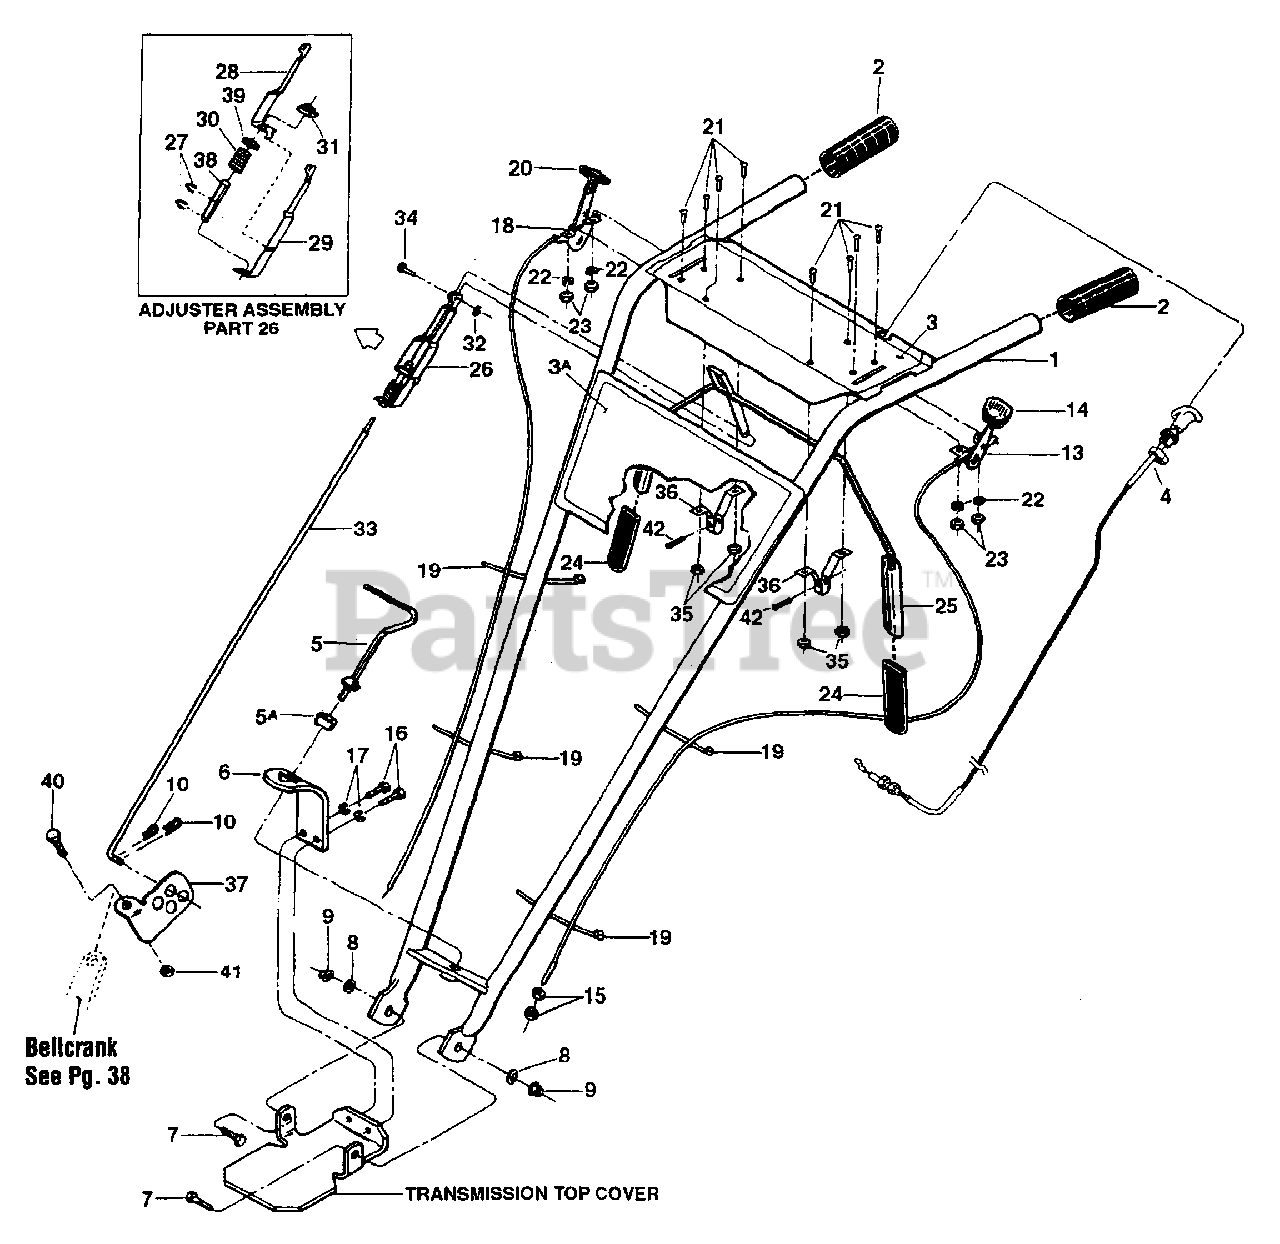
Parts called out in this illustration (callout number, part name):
1	Handlebars
2	Grip
3	Decal, Control Panel
3A	Decal, Model Name/Logo
4	Reverse Clutch Control Cable
5	Height Adjustment Handle
5A	Washer, Keyed
6	Bracket, Handlebar Height Adjustment
7	Hex Hd. Screw, 3/8-16 x 1
8	Washer, Plain (flat) 3/8, S.A.E.
9	Hex Locknut, 3/8-16
10	Hair Pin Cotter
13	Wheel Gear Control and Cable Assy.
14	Knob, Wheel Gear Control Lever
15	Hex Nut, 5/16-24
16	Hex Hd. Screw, 3/8-16 x 3/4
17	Lockwasher, 3/8
18	Engine Throttle Control and Cable
19	Cable Ties, Plastic
20	Knob, Throttle Control Lever
21	Round Hd. Screw, #10-32 x 1/2
22	Lockwasher, #10
23	Hex Nut, #10-32
24	Grip
25	Bail, Forward Clutch Control
26	Adjuster Assy.
27	Klip Ring
28	Adjuster, Right Side
29	Adjuster, Left Side
30	Spring, Adjuster
31	Rectangular Nut
32	Klip Ring
33	Rod, Forward Clutch
34	Clevis Pin
35	Sems Nut
36	Bracket, Bail Support
37	Swivel
38	Bushing
39	Washer
40	Hex Hd. Screw, 1/4-20 x 3/4
41	Nut, 1/4-20
42	Hex Flange Screw, self-tapping, 1/4-20 x 1/2
